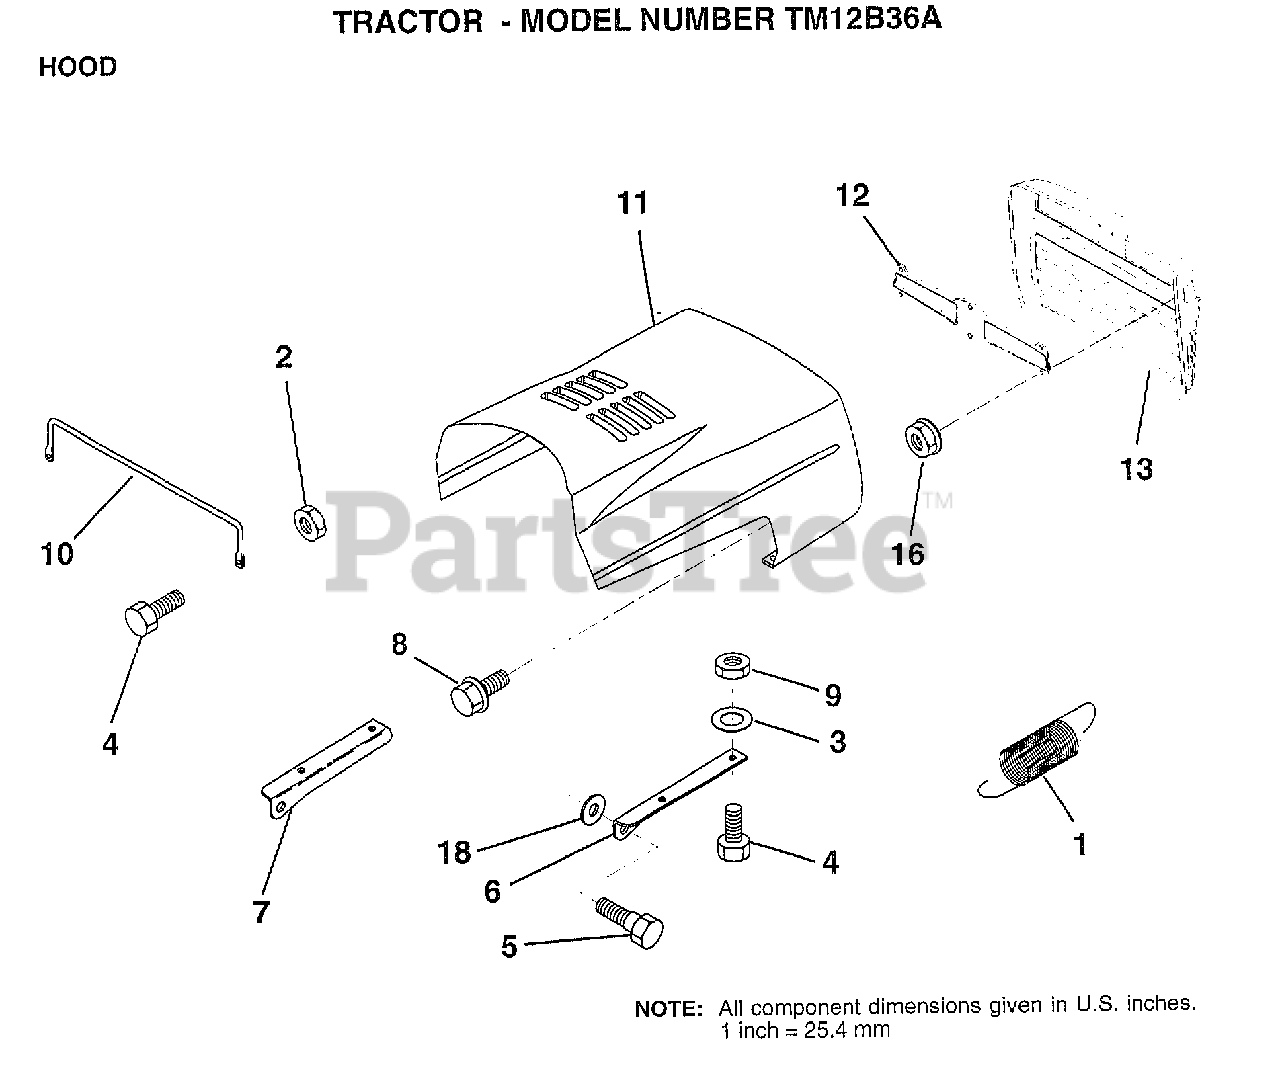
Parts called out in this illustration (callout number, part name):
1	EXT SPRING
2	NUT HXKEP 1/4X20
3	WASHER
5	BOLT.SHLD.5/16-18
6	BRKT HOOD RH
7	BRKT HOOD LH
8	SCREW SLTD HXHD
9	NUT
10	"BRACE,HOOD"
11	HOOD
13	GRILLE.P/L.MOLD.MS.(RED)
16	NUT
18	WASHER
